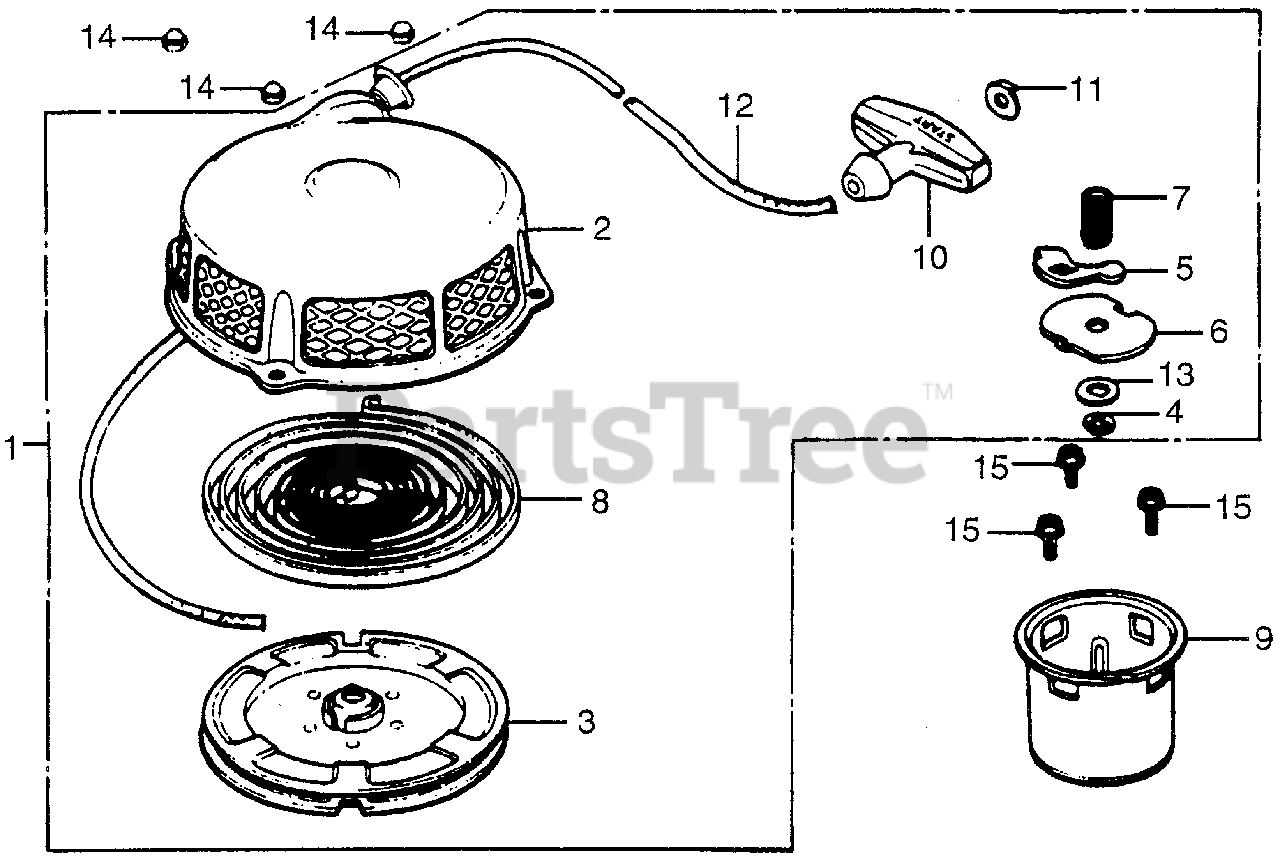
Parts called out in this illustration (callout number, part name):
1	STARTER ASSY., RECOIL *R8* (BRIGHT RED)
2	STARTER ASSY., RECOIL *R8* (BRIGHT RED)
3	PULLEY, RECOIL STARTER
4	E-RING (NOT AVAILABLE)
5	RATCHET, STARTER (NOT AVAILABLE)
6	PLATE, FRICTION (NOT AVAILABLE)
7	SPRING, FRICTION (NOT AVAILABLE)
8	SPRING, RETURN
9	PULLEY, STARTER (NOT AVAILABLE)
10	KNOB, STARTER
11	STOPPER, ROPE (NOT AVAILABLE)
12	ROPE, STARTER (#5X55")
13	WASHER (NOT AVAILABLE)
14	NUT, CAP (6MM)
15	BOLT, FLANGE (6X12)
